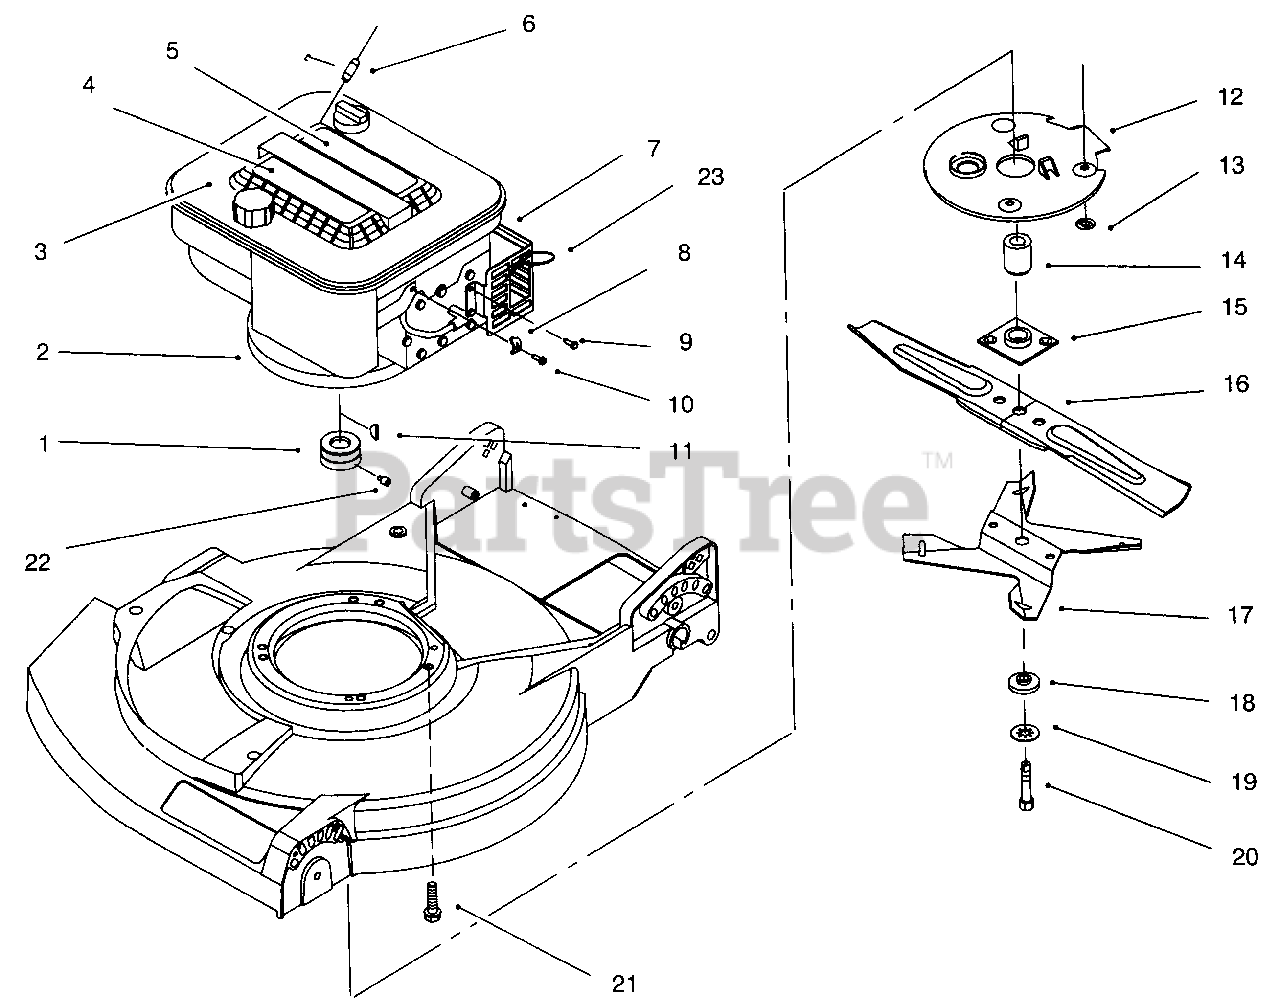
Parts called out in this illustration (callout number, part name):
1	Pulley-Engine (Model No.10517 & 10522)
2	Engine
3	Grille-Engine
4	Decal-Recoil (Model No.10418)
5	Decal-Recoil (Model No.10522)
5	Decal-Recoil (Model No.10418 & 10517)
6	Stop-Rope
7	Shield-Muffler
8	Clamp-Cable
9	Screw-Hex. Hd.
11	Key-Woodruff (Model No.10418)
11	Key-Woodruff (Model No.10517 & 10522)
12	Shield-Grass (Model No.10517 & 10522)
13	Nut-Push (Model No.10517 & 10522)
14	Hub-Blade Driver
15	Plate-Blade Driver
16	Blade-21 "
17	Fan-Mulching
19	Washer-Lock
20	Bolt-Blade
21	Screw
22	Screw-Set (Model No.10517 & 10522)
23	Strap-Tie
